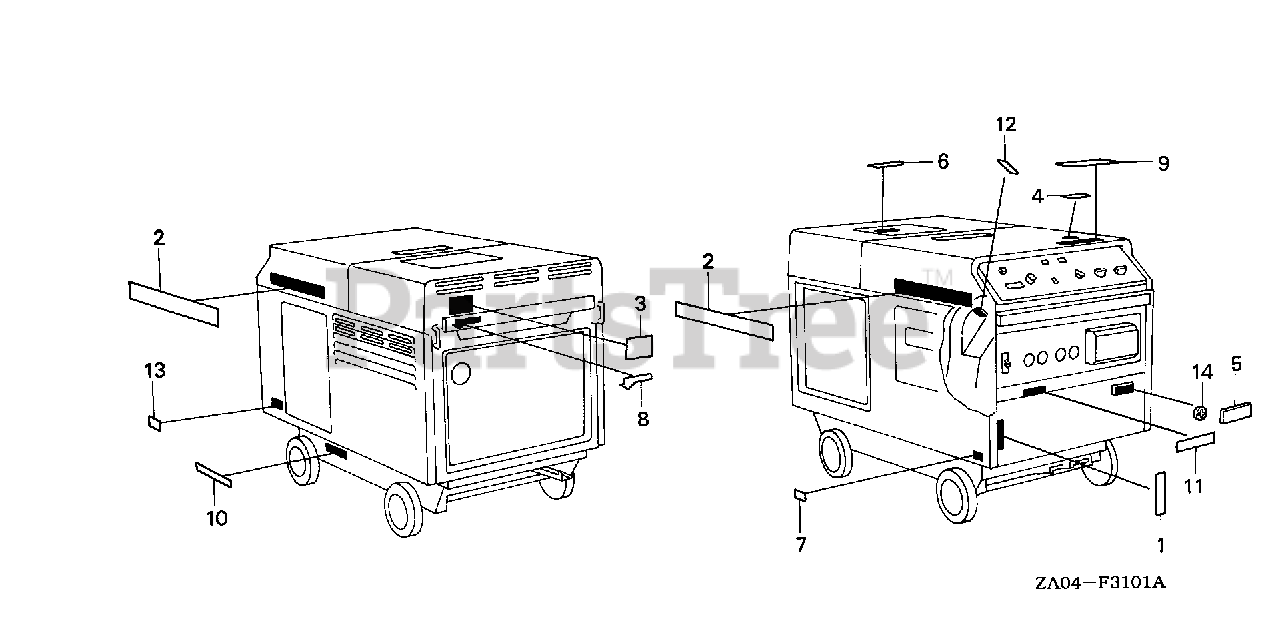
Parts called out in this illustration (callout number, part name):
2	EMBLEM (NOT AVAILABLE)
3	MARK, SPECIFICATION
5	EMBLEM (LIQUID COOLED ENGINE)
6	MARK, CAUTION (ENGLISH/FRENCH/SPANISH)
7	MARK, GROUND
8	MARK, EX. CAUTION (ENGLISH/FRENCH)
9	MARK, CAUTION
10	MARK, DRAIN
13	MARK, OIL CAUTION
14	NUT, SPEED (3MM)
